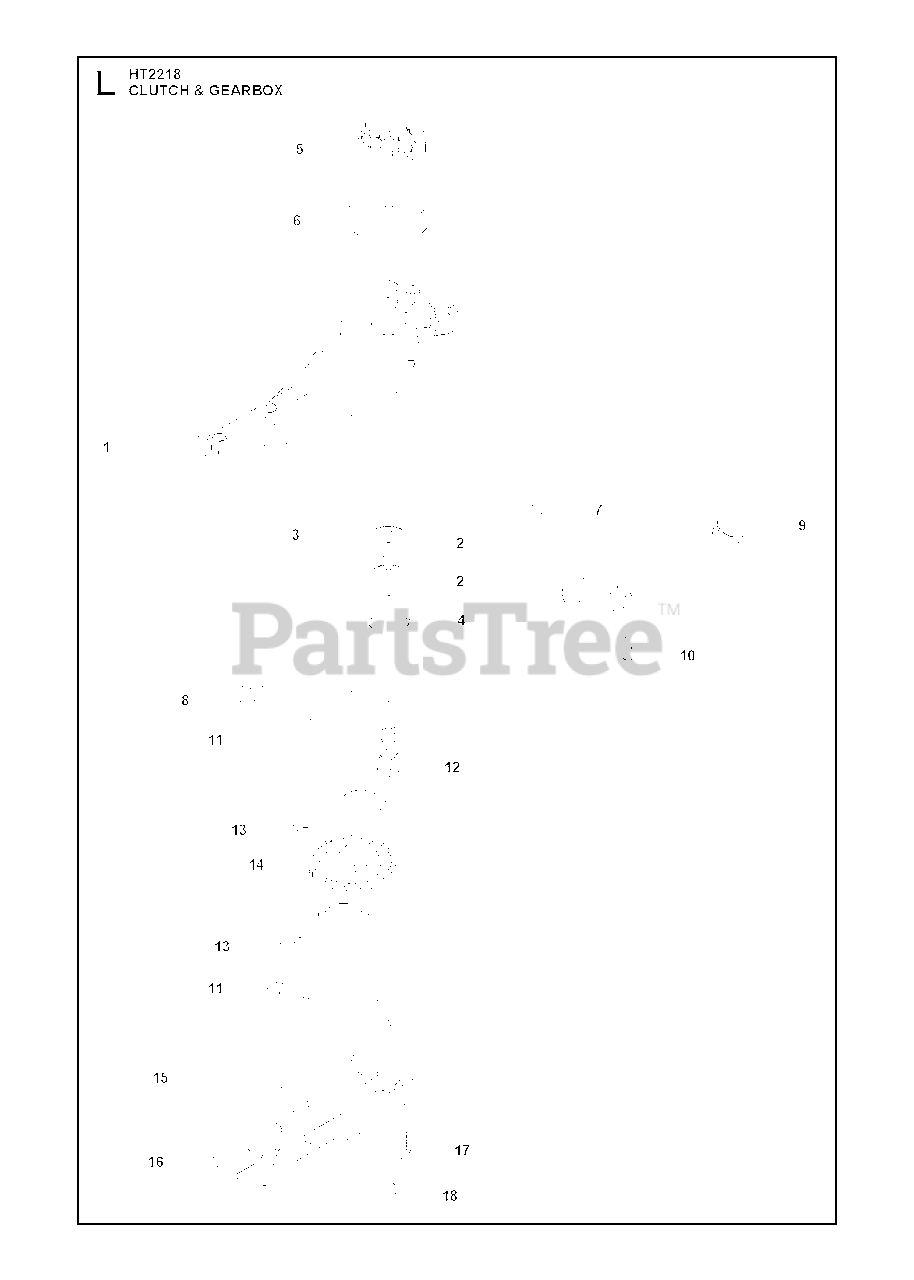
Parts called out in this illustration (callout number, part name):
1	GEAR HOUSING ASSY
2	BALL BEARING
3	PIN
4	CIRCLIP
5	CLUTCH ASSY
6	CLUTCH DRUM ASSY
9	EXHAUST PIPE ASSY.
11	WEAR PLATE
12	GEAR WHEEL SHAFT
13	CONNECTING ROD
14	GEAR WHEEL
